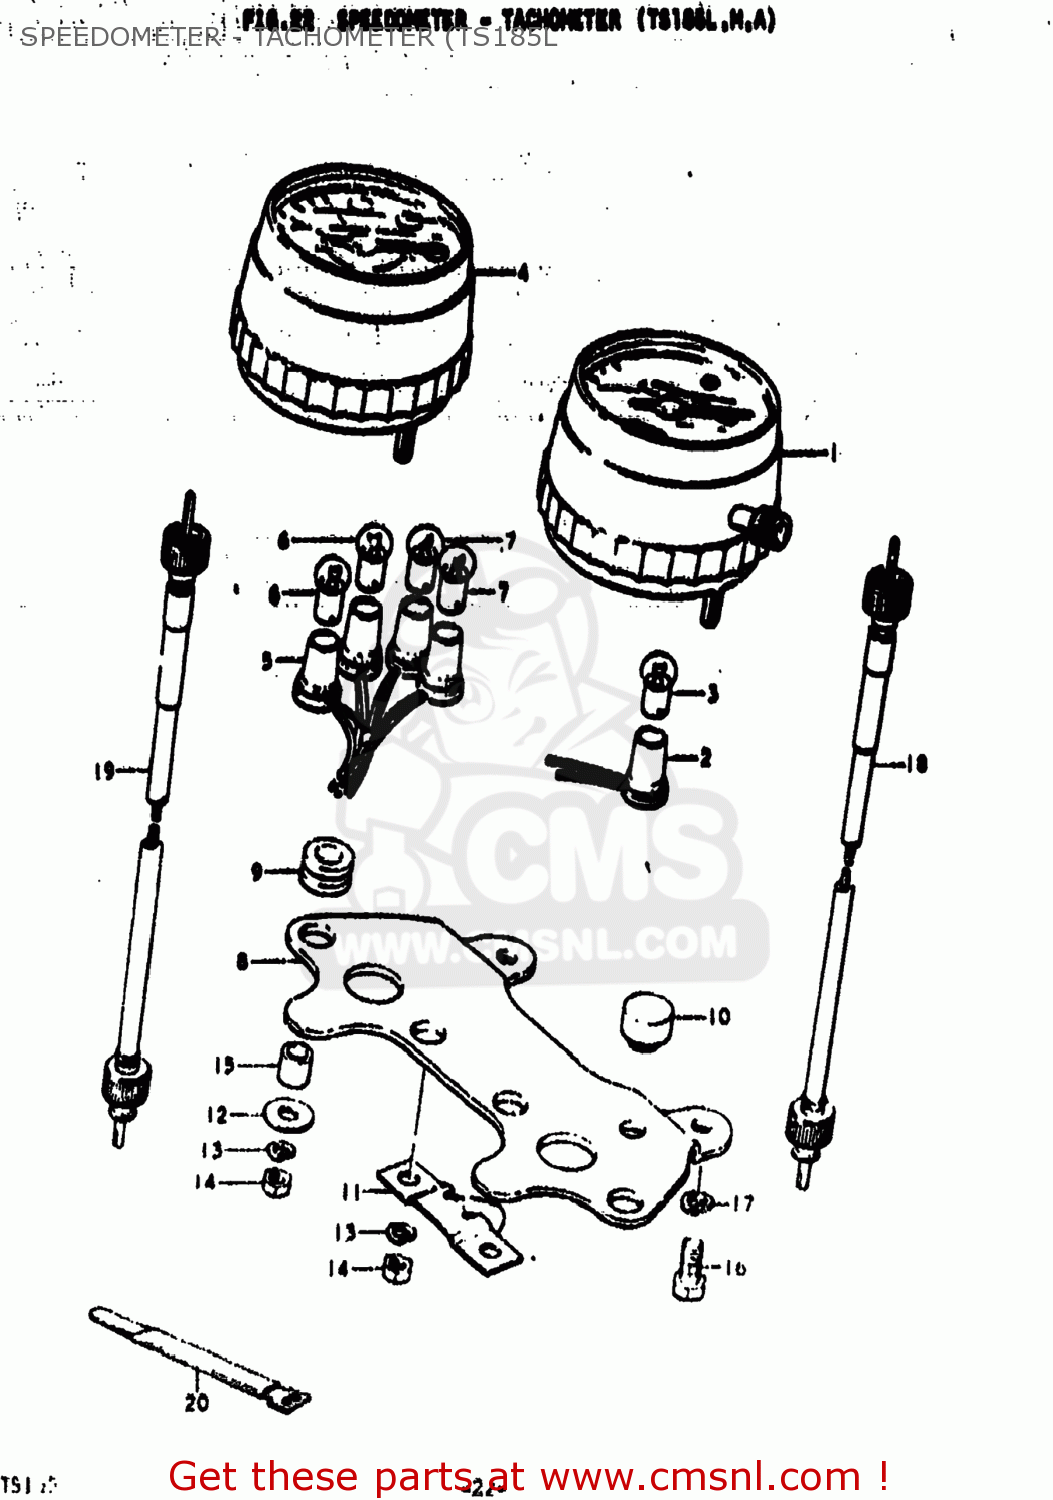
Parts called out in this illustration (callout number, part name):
0	SPEEDOMETER ASSEMBLY
1	SPEEDOMETER ASSEMBLY
2	SOCKET,METER
3	BULB(6V/3W)
4	METER,TACHOMETER
5	SOCKET,TACHOMETER
6	BULB(6V/3W)
7	BULB(6V1.7W,STANLEY,A61A)
8	BRACKET,METER
9	CUSHION
10	CUSHION,METER
11	COVER,METER,UNDER
12	WASHER (5.5X16X1.2)
13	LOCK WASHER
14	NUT
15	SPACER,METER NO.2
16	BOLT
17	LOCK WASHER
18	CABLE ASSEMBLY,SPEEDOMETER
19	CABLE ASSY,TACHOMETER
20	CLAMP
